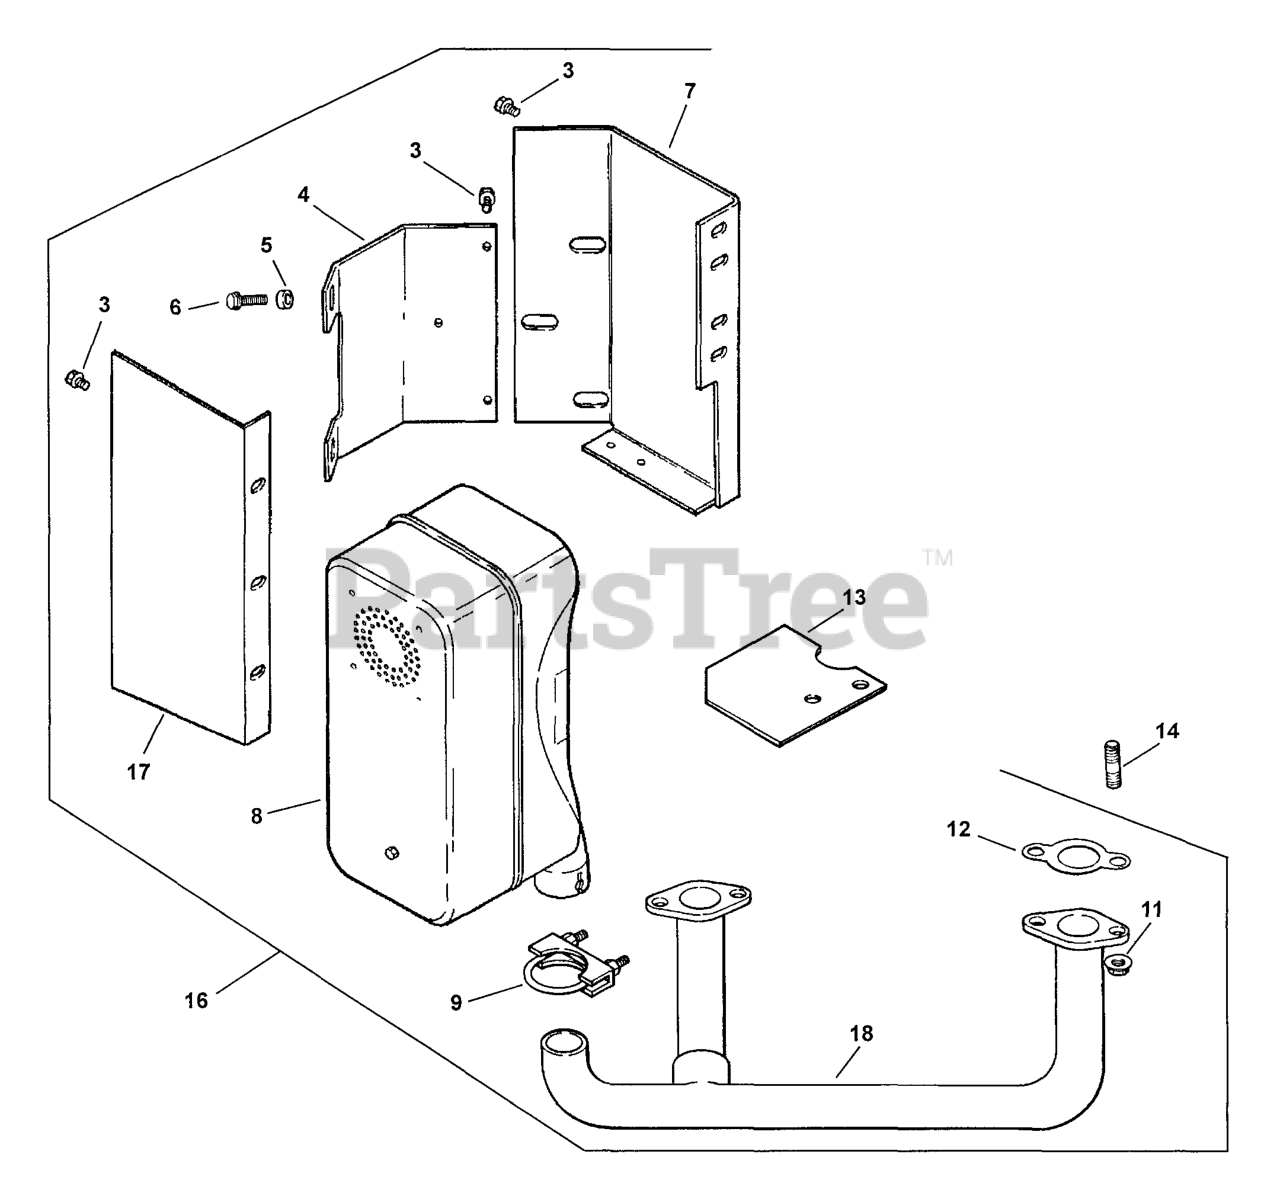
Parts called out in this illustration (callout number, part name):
3	SCREW - USE M-645016
6	SCREW - USE M-651030
11	NUT - USE M-841080
14	STUD - USE M-829033
